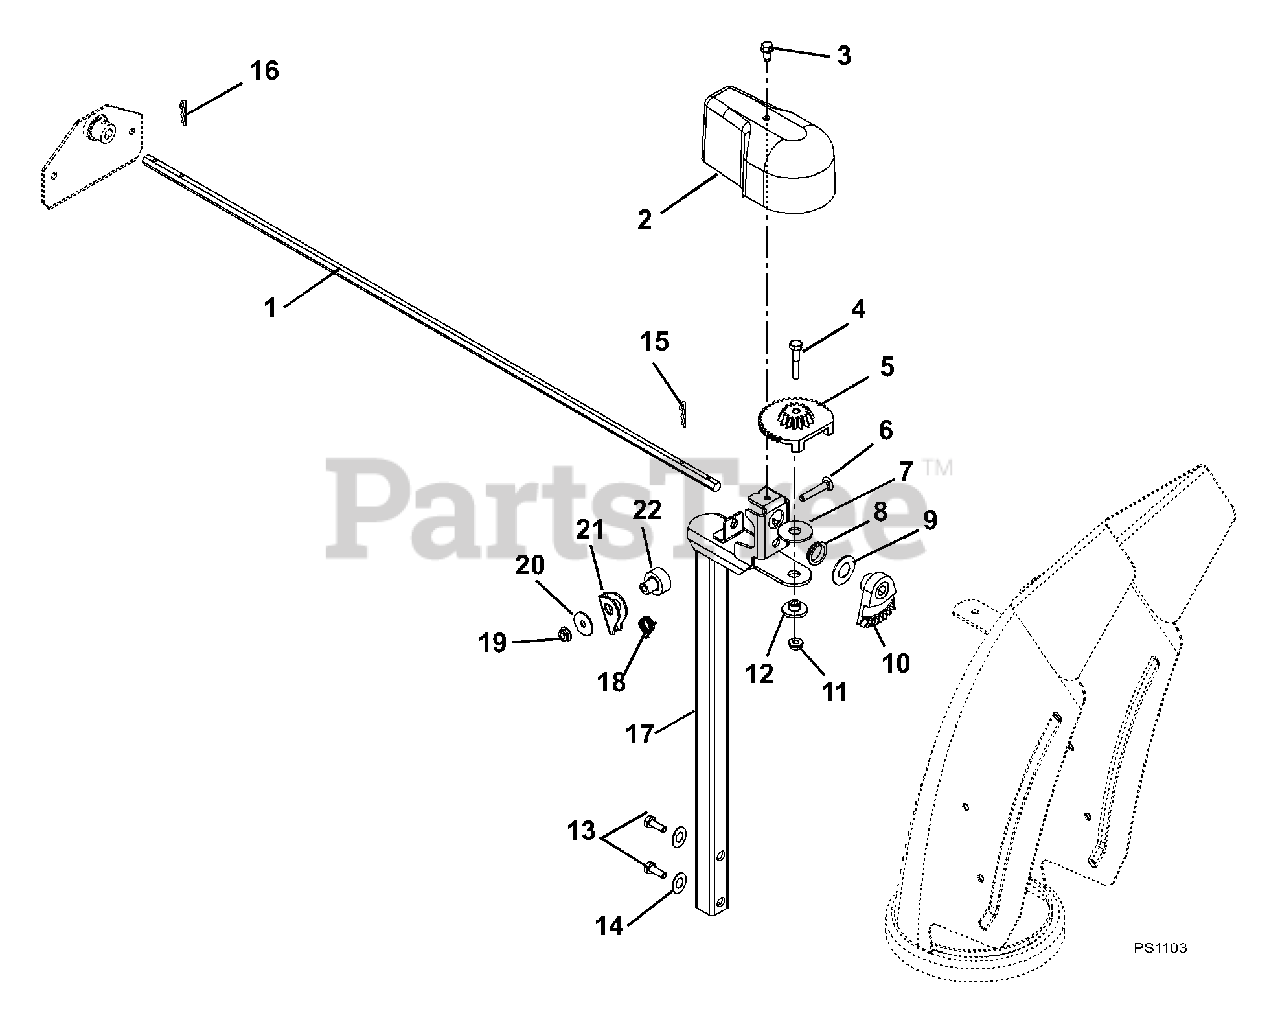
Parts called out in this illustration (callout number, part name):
1	ROD, CHUTE ROTATION-HEX
2	COVER, CHUTE GEAR
3	@SCR-TAP .25-20X.50 HWH TR YWZ
4	@BLT-HEX .25-20X1.50 GR5 YWZC
5	GEAR, CHUTE
6	@BLT-RDHDSQNK .25-20X1.50 G5YZ
7	WSHR-FL-NYL .47X1.38X.09
8	BUSHING, POLYLINER-.75 SNAPIN
9	WSHR-FL-STL.754X1.125X.062YWZC
10	ARM, LOCKING
11	@NUT-LK-TOP-FLG .25-20 YWZC
12	BSHG-FLG .265X.448X.375X1.00
13	@BLT-HEX .38-16X1.75 GR5 YWZC
14	@WSHR-LK .38X.094 REG YWZC
15	CLIP, SPRING
16	HAIRPIN, #7 CLIP .094X2.31 YWZ
17	PEDESTAL, CHUTE SUPPORT
18	SG-TORS
19	@NUT-LK-TOP-FLG .25-20 YWZC
20	WSHR-FL-STL .281X1.000X.063
21	ARM, LOCKING
22	BUSHING, POLYLINER-.75 SNAPIN
